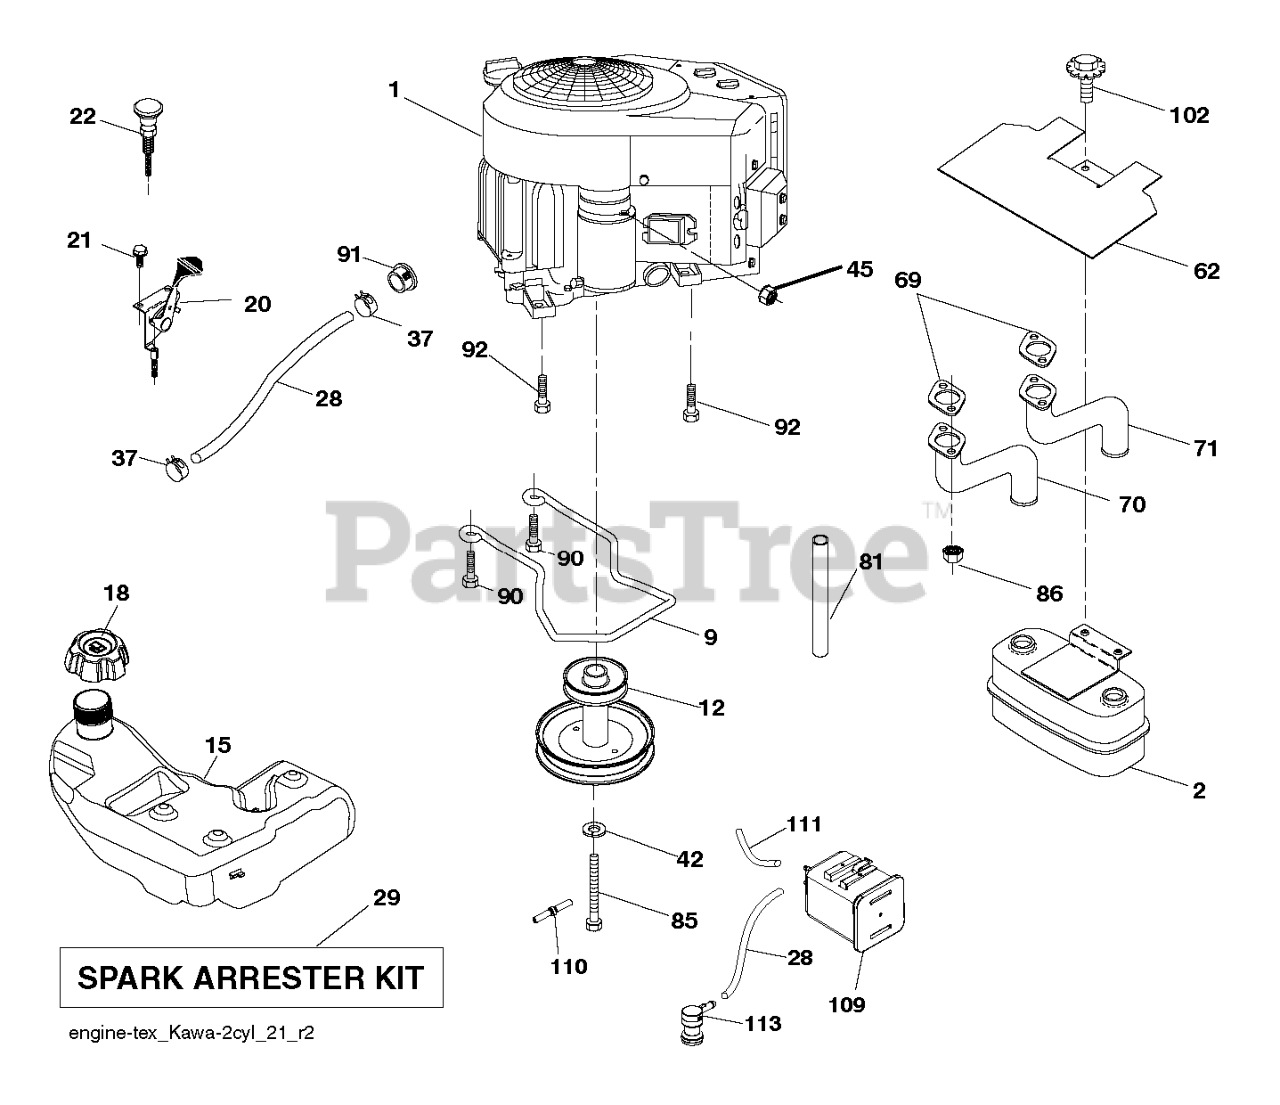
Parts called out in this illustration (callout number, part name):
2	MUFFLER.ASM.TWIN.MNTG.BRACKET
9	KEEPER.BELT.ENG.4.25"2.BLT.431
12	ENGINE.PULLEY
15	TANK.ASM.FUEL.3GA.CARB.17
18	FUEL CAP
18	CAP ASSY FUEL 3" GRAY
20	CONTROL.THROTTLE.COBRA.BLACK
21	SCREW.#10 X 0.750.BOS
22	CONTROL, CHOKE
28	LINE.FUEL.64"REAR.EMIS
29	KIT.SPARK ARRESTOR 794945 B&S
37	HOSE CLAMP
42	WASHER 7/16 LOCK
45	NUT
62	SHIELD.HEAT.MUFFLER
70	TUBE.EXHAUST.RH.FR961/FR730
71	TUBE.EXHAUST.LH.FR961/FR730
81	TUBE, DRAIN OIL ASM.
85	BOLT.HEX.7/16-20X4.GR5.1.5BLUE
86	NUT.HEX.FLANGE.TOPLOCK
90	SCREW 3/8-16X1
91	BUSHING.1.375OD
92	SCREW 3/8-16X1
102	SCREW
109	CANNISTER, CARBON
110	VALVE.ASM.ANTI-SLOSH
111	RP PURGE LINE
113	VALVE.SLANT.CARTRDG.90 DEG.TEX
